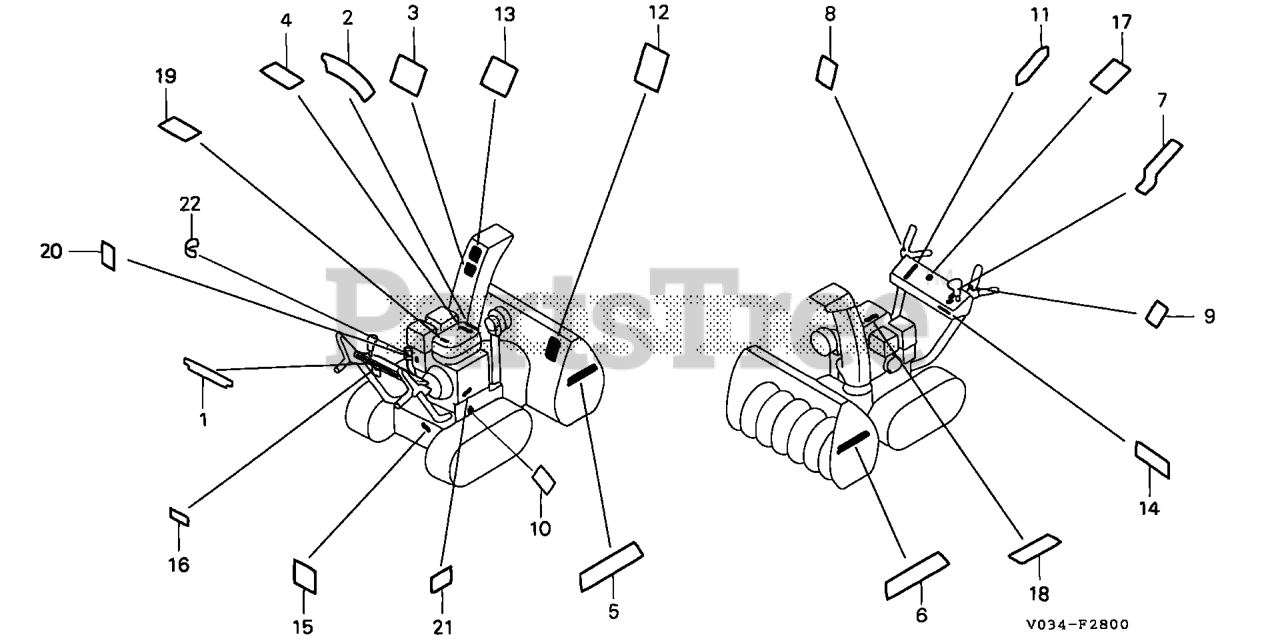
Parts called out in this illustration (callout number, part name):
1	LABEL, OPERATION
2	MARK, HONDA EMBLEM
3	LABEL, WARNING (ENGLISH)
4	LABEL, WARNING FUEL (ENGLISH)
5	MARK, R. STRIPE
6	MARK, L. STRIPE
7	MARK, CHANGE INDICATION
8	MARK, AUGER CLUTCH (ENGLISH)
9	MARK, CLUTCH (ENGLISH)
10	MARK, HEIGHT ADJUSTING
11	MARK, CHUTE CONTROL OPERATION (ENGLISH)
12	MARK, HOUSING DANGER (ENGLISH)
13	MARK, DISCHARGE DANGER (ENGLISH)
14	MARK (H.S.T.)
15	MARK, INDICATION (H.S.T.)(ENGLISH)
16	MARK, CHOKE INDICATION (ENGLISH)
17	MARK, THROTTLE (ENGLISH)
18	MARK, EX. CAUTION (ENGLISH)
19	MARK, FUEL INDICATION (PICTOGRAPH)
20	MARK, FUEL INDICATION (ENGLISH)
21	MARK, OIL CAUTION (ENGLISH)
22	LABEL, OIL RECOMMENDATION (ENGLISH)
